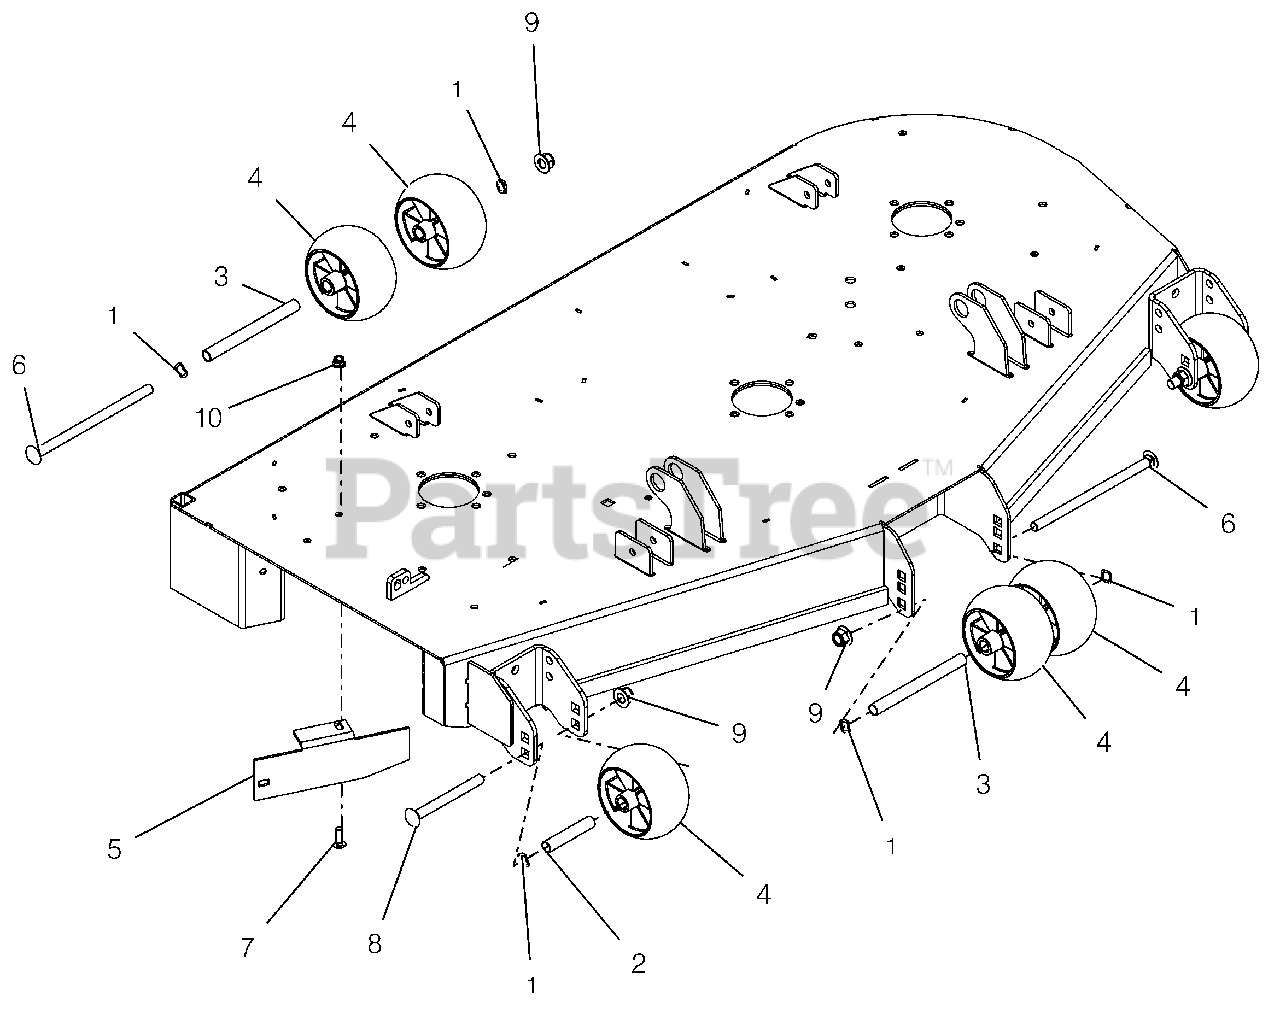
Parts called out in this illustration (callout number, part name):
1	WAVE WASHER .531X.781X.125FH
2	SPACER, .510X.625X3.35
3	SPACER, .510X.625X6.50
4	ANTI-SCALP WHEEL - 5X3 CTR
5	BAFFLE, DISCHARGE, 52"
6	@BLT-RDHDSQNK .50-13X8.50 G5YZ
7	@BLT-RDHDSQNK .31-18X1.00 G5YZ
8	BLT-RDHDSQNK .50-13X5.00 GR5YZ
9	@NUT-LK-NYL-FLG .50-13 YWZC
10	@NUT-LK-NYL-FLG .31-18 YWZC
